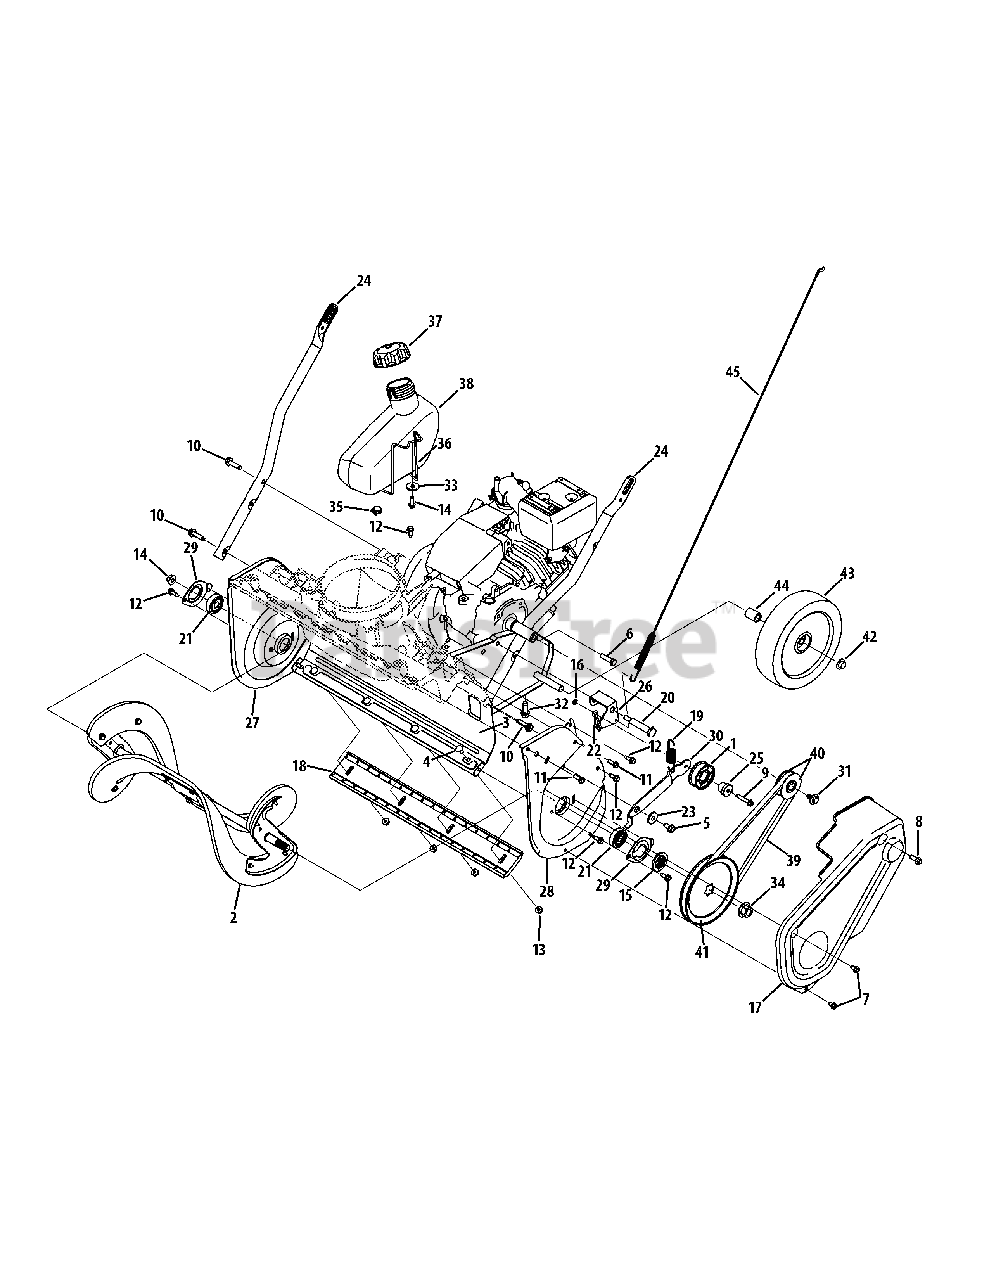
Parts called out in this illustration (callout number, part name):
1	Idler Pulley Assembly
2	Auger Assembly Complete
2	Rubber Auger Paddle Kit
2	Hex Washer Screw, 1/4-20 x .750
2	Center Auger Bracket
2	Hex Washer Bolt 1/4-20 x.750
3	Frame Assembly
4	Carriage Screw, 1/4-20 x .62
5	Hex Washer Screw, 5/16-18 x .750
6	Hex Screw, 5/16-24 x 1.25
7	Hex Washer Screw, 1/4-20 x .500
8	Hex Lock Screw, 5/16-24 x .750
9	Hex Washer Screw, 1/4-20 x 1.500
10	Hex Washer Screw, 5/16-18 x 1.250
11	Hex Washer Screw, 1/4-15 x .750
12	Hex Washer Screw, 1/4-20 x .625
13	Flange Lock Nut, 1/4-20
14	Flange Lock Nut, 3/8-16
15	Pulley Hub
16	Push Nut, .25 x .50
17	Belt Cover
18	Shave Plate
19	Extension Spring, .70 x 3.035
20	Shoulder Bolt, 5/16-24 x .496 x 2.18
21	Ball Bearing, .5000 x 1.375 x .4375
22	Drive Cable Wire Support
23	Shoulder Spacer
24	Lower Handle
25	Shoulder Spacer
26	Idler Cable Bracket
27	RH Side Plate
28	LH Side Plate
29	Bearing Cup
30	Idler Bracket
31	Hex Lock Screw, 5/16-24 x .750
32	Hex Washer Screw, 3/8-16 x 1.000
33	Hex Washer Screw, 1/4-15 x .750
34	Flange Nut, 7/16-20
35	Hose Clamp, .490
36	Gas Tank Wire Support
37	Fuel Cap
38	Fuel Tank
39	Belt, .500 x 35.06
40	Pulley Half, .625 x 2.25
41	Pulley
42	Push Cap, 1/2
43	Wheel, 8"
44	Spacer, .525 x .775 x .835
45	Clutch Cable
